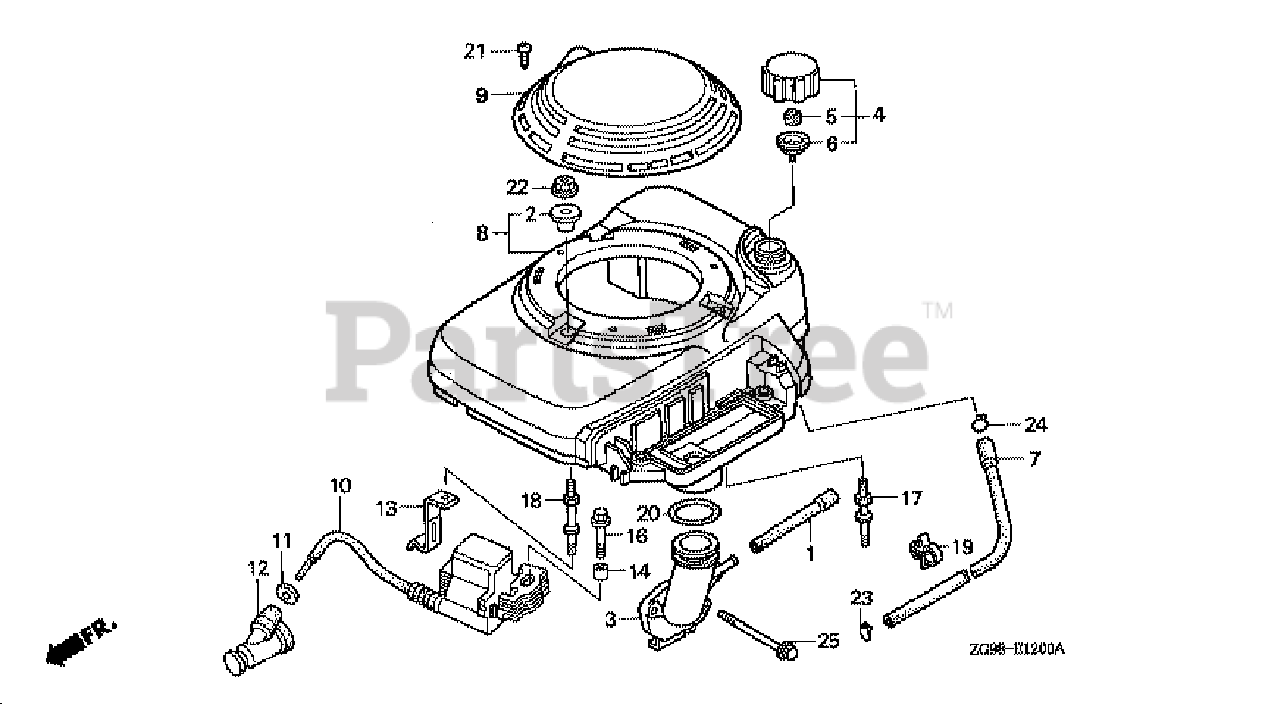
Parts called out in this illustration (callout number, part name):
1	TUBE, BREATHER
2	COLLAR, AIR CLEANER
3	ELBOW, AIR CLEANER
4	CAP ASSY., FUEL TANK
5	SPONGE, FUEL CAP BREATHER
6	GASKET, FUEL CAP
7	TUBE, FUEL TANK
8	COVER, FAN *NH1* (BLACK)
9	HOOD, FAN COVER *NH1* (TEXTURED) (BLACK)
10	COIL ASSY., IGNITION
11	GROMMET, IGNITION WIRE
12	CAP ASSY., NOISE SUPPRESSOR
16	BOLT, FLANGE (6X25)
17	BOLT A, STUD
18	BOLT B, STUD
19	CLIP B, CABLE
20	O-RING (33.3X3.5)
21	SCREW, TAPPING (4X20)
22	NUT, FLANGE (6MM)
23	CLIP, TUBE (B8)
24	CLIP, TUBE (B10)
25	BOLT, FLANGE (6X100)
